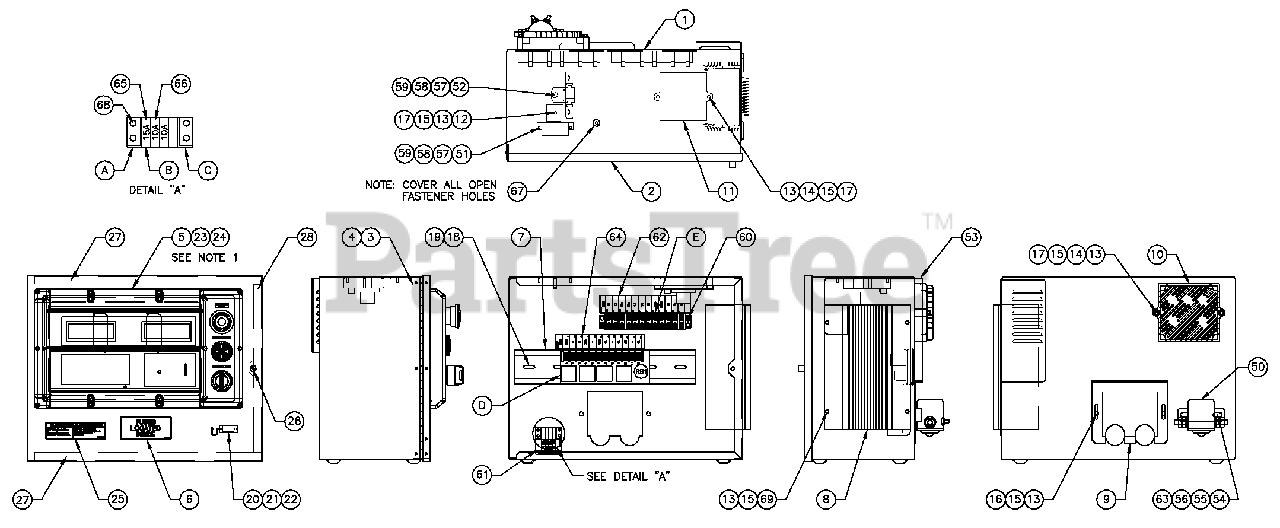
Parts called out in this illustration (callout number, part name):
1	ENCL H/G CONTROL PANEL
2	COVER CONTROL PANEL
3	HINGE CONTINUOUS H PANEL
4	RIVET POP .125X.275SS
5	ASSY PROGRAMMED H-100
6	DECAL FUSES LOCATED INSIDE
7	RAIL SNAPTRACK PCB HOLDER BULK (12"LG)
8	ASSY PCB 10A UL BATT CHRGR12V
9	PLATE HARNESS CLAMP
10	ASSY PCB PWRAVRW/AMP HEADER
11	ASSY PCB BOSCH GOV DRIVER
12	DIO BRIDGE 25A 600V
13	WASHER LOCK M5
14	SCREW PPHM M5-0.8X 30 SS
15	WASHER FLAT M5
16	SCREW HHPM M5-0.8X 12
17	NUT HEX M5-0.8 G8 YEL CHR
18	WASHER FLAT M4
19	SCREW PHTT M4-0.7X 10 ZYC
20	CONN DUST CAP W/CHAIN DB9
21	WASHER FLAT M3.5
22	SCREW PHTT M3.5-0.6 X 10
23	SCREW PPHM M4-0.7 X 8 BLX OX
24	WASHER LOCK #8-M4
25	DECAL WRN BATT CHRG12/24V BI
26	M5-0.8 CAPTIVE PANEL KNLD HD
27	SEAL COVER 3.18 X 12.7 X 382
28	SEAL COVER 3.18 X 12.7 X 283
50	RELAY CONTACTOR 12VDC
53	COVER CONTROL PANEL SIDE
54	SCREW HHC 1/4-20 X 3/4 G5
55	WASHER FLAT M6-1/4
56	WASHER LOCK M6-1/4
57	WASHER LOCK M3
58	NUT HEX M3-0.5 G8 YEL CHR
59	WASHER FLAT M3
60	SCREW PHTT #6-32 X 5/8 ZYC
61	DECAL CPL CONTROL PANEL FUSES
62	DECAL CPL 5.4/6.8LTB3
63	NUT HEX 1/4-20 STEEL
64	DECAL CPL 5.4/6.8L RELAY BOARD
65	FUSE ATO TYPE 15 AMP (BLUE)
66	FUSE ATO TYPE 10 AMP (RED)
67	SEAL WEATHER .45"DIA
68	SCREW PHTT #6-32 X 3/8 ZYC
69	SCREW PHTT M5-0.8X 16 ZYC
A	ADPTRRH SIDE WICKMANN 178.6191
B	HOLDER FUSE WICKMANN 178.6150
C	ADPTRLH SIDE WICKMANN 178.6192
D	ASSY PCB G-PANEL RELAY 12VDC
E	BLOCK TERM 2 0A 12 X 6X 1 10 0V
